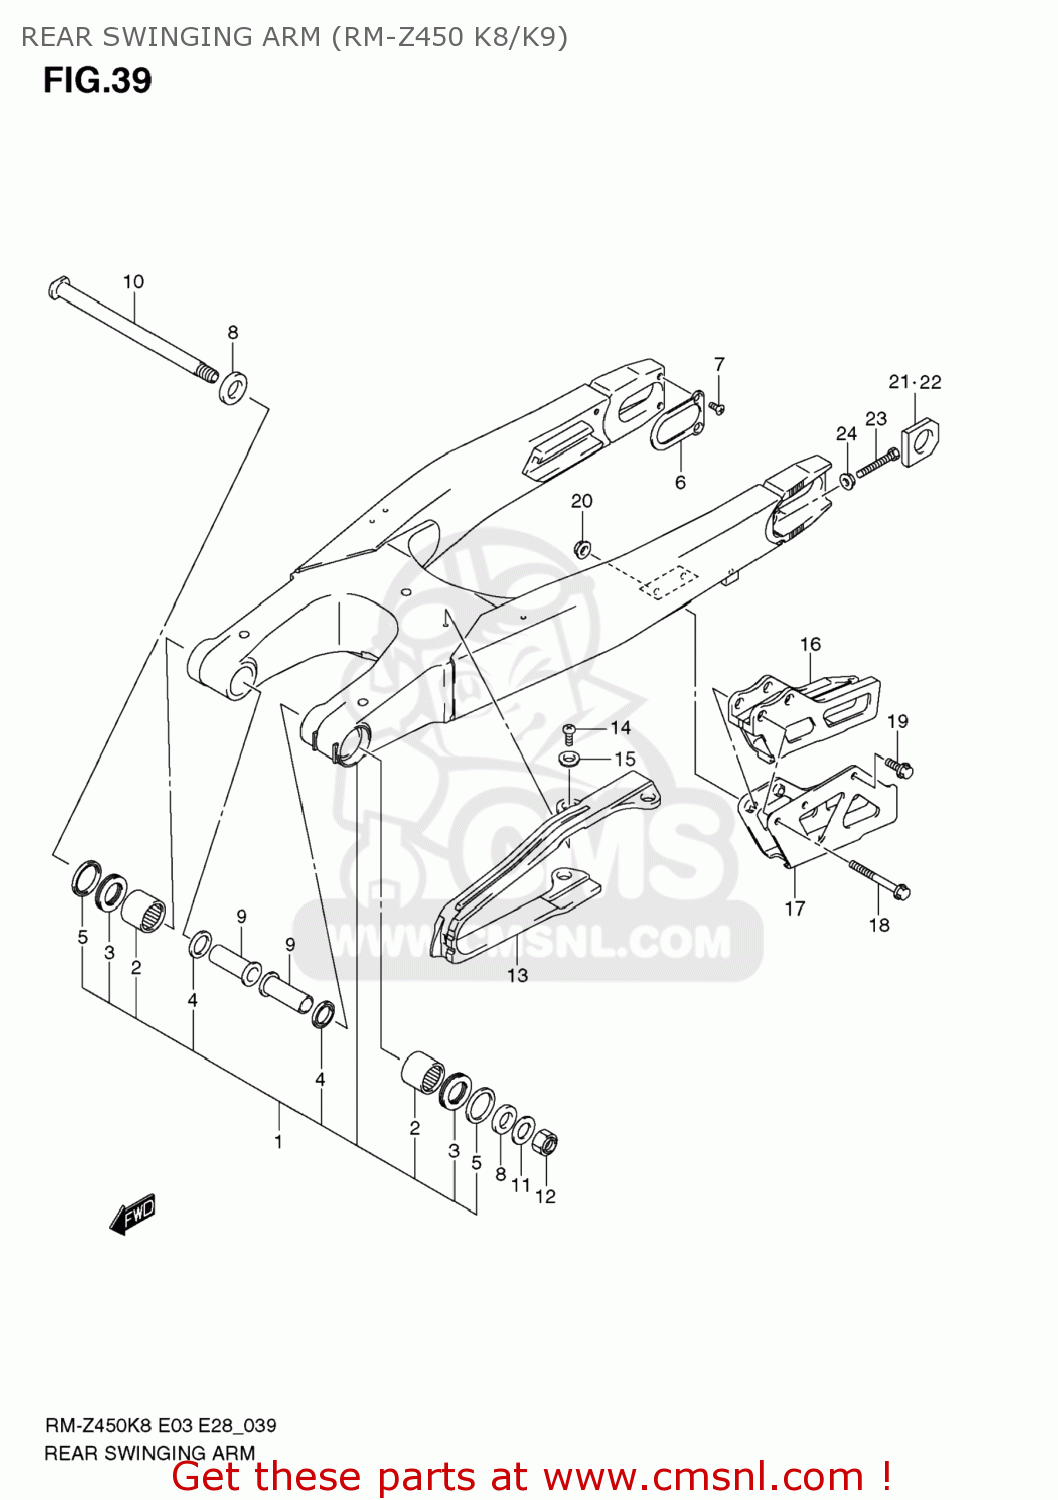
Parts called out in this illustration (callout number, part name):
1	SWINGINGARM ASSY,RR
2	BEARING(22X29X30)
3	BEARING(22X35X2)
4	SEAL,OIL(22X29X4)
5	SEAL,RR SWGARM PIVOT OUTER
6	PLATE,SWING ARM RR
7	SCREW
8	SPACER,RR SWGARM PIVOT OUTER
9	SPACER,SWGARM PIVOT INNER
10	SHAFT,RR SWINGINGARM PIVOT
11	WASHER
12	NUT
13	BUFFER,CHAIN TOUCH DEFENSE
14	SCREW
15	WASHER
16	GUIDE,CHAIN
17	PLATE,CHAIN GUIDE
18	BOLT(6X45)
19	BOLT(6X12)
20	NUT
21	WASHER,CHAIN ADJUSTER,R
22	WASHER,CHAIN ADJUSTER,L
23	BOLT(8X50)
24	NUT
